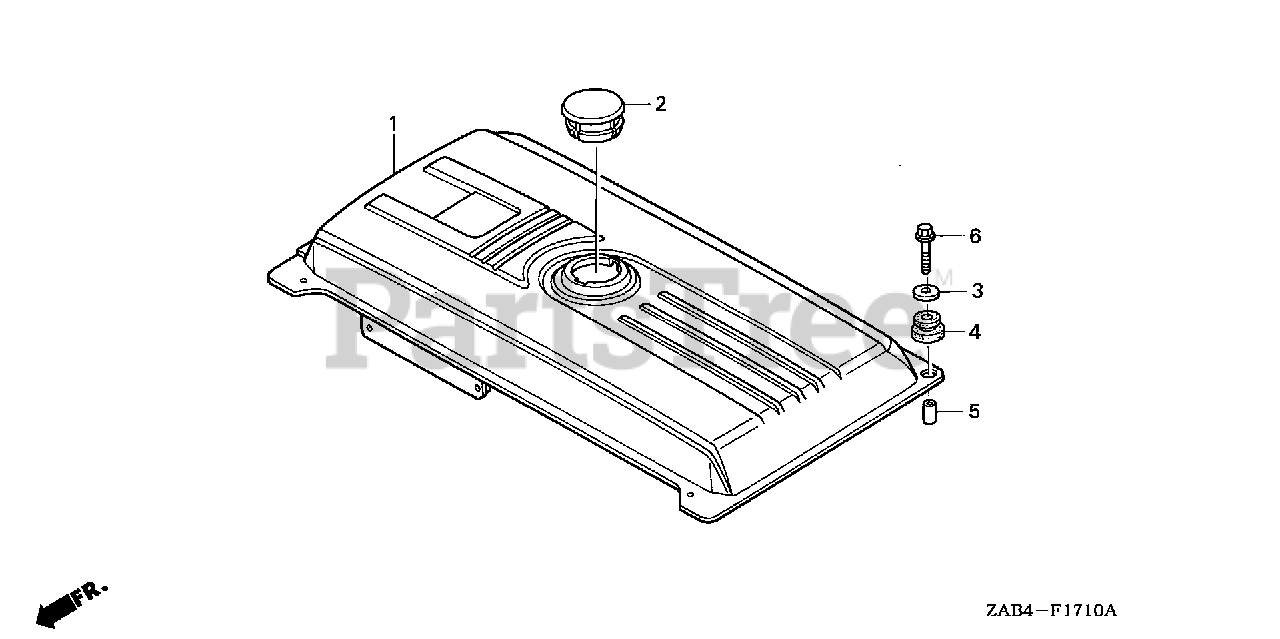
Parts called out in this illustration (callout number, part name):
1	COVER, TOP *R8* (BRIGHT RED)
2	CAP, GENERATOR TOP COVER
3	WASHER, TANK RUBBER
4	CUSHION, TANK RUBBER
5	COLLAR, TANK RUBBER
6	BOLT, FLANGE (6X22)
